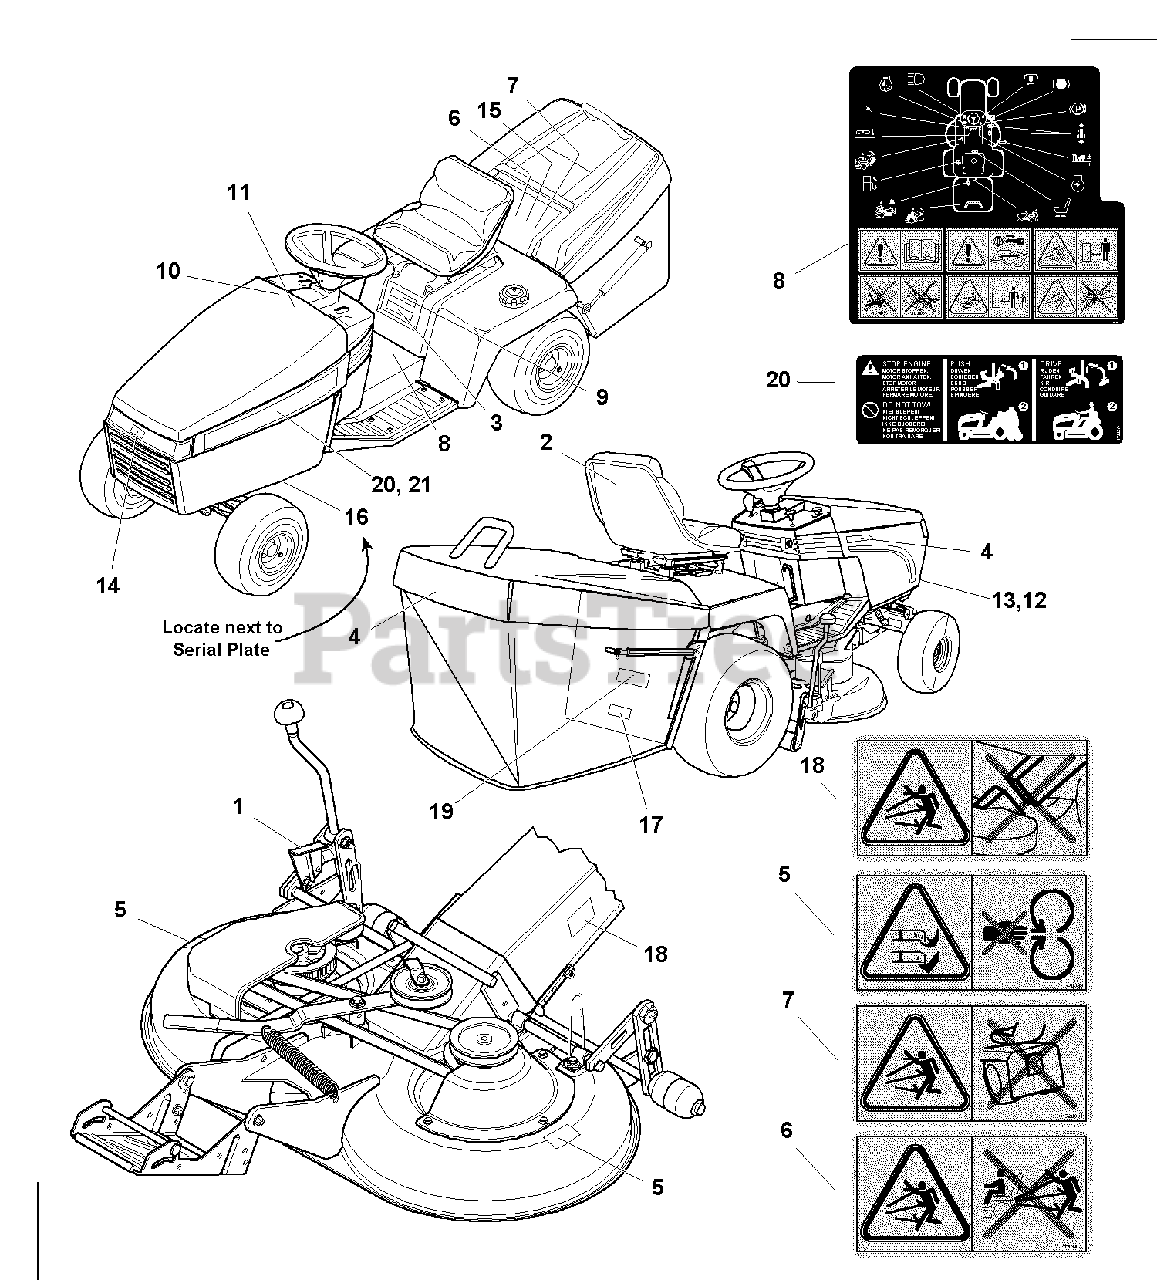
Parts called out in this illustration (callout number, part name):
1	DECAL, Cutting Height
2	DECAL, Logo, USA
3	DECAL, Engine, 18V-Twin
4	DECAL, Simplicity w/Logo, Fuel Resistant
5	DECAL, Danger, Rotating Blades
6	DECAL, Danger, Catcher Open
7	DECAL, Danger Operating w/o Catcher
8	DECAL, Operating Instructions Symbols
9	DECAL, Baron
10	DECAL, Touch Up Paint
11	DECAL, Drive Belts/Mower Blades
12	DECAL, Hood Stripe L H
13	DECAL, Hood Stripe R H
14	DECAL, Simplicity Logo
15	DECAL, Danger Hopper Lid
16	DECAL, GS-Safety
17	DECAL, Drawbar
18	DECAL, Danger, Discharge Tube
19	DECAL, Transmission Release Valve
20	DECAL, Massey Ferguson Hood L H
21	DECAL, Massey Ferguson Hood R H
